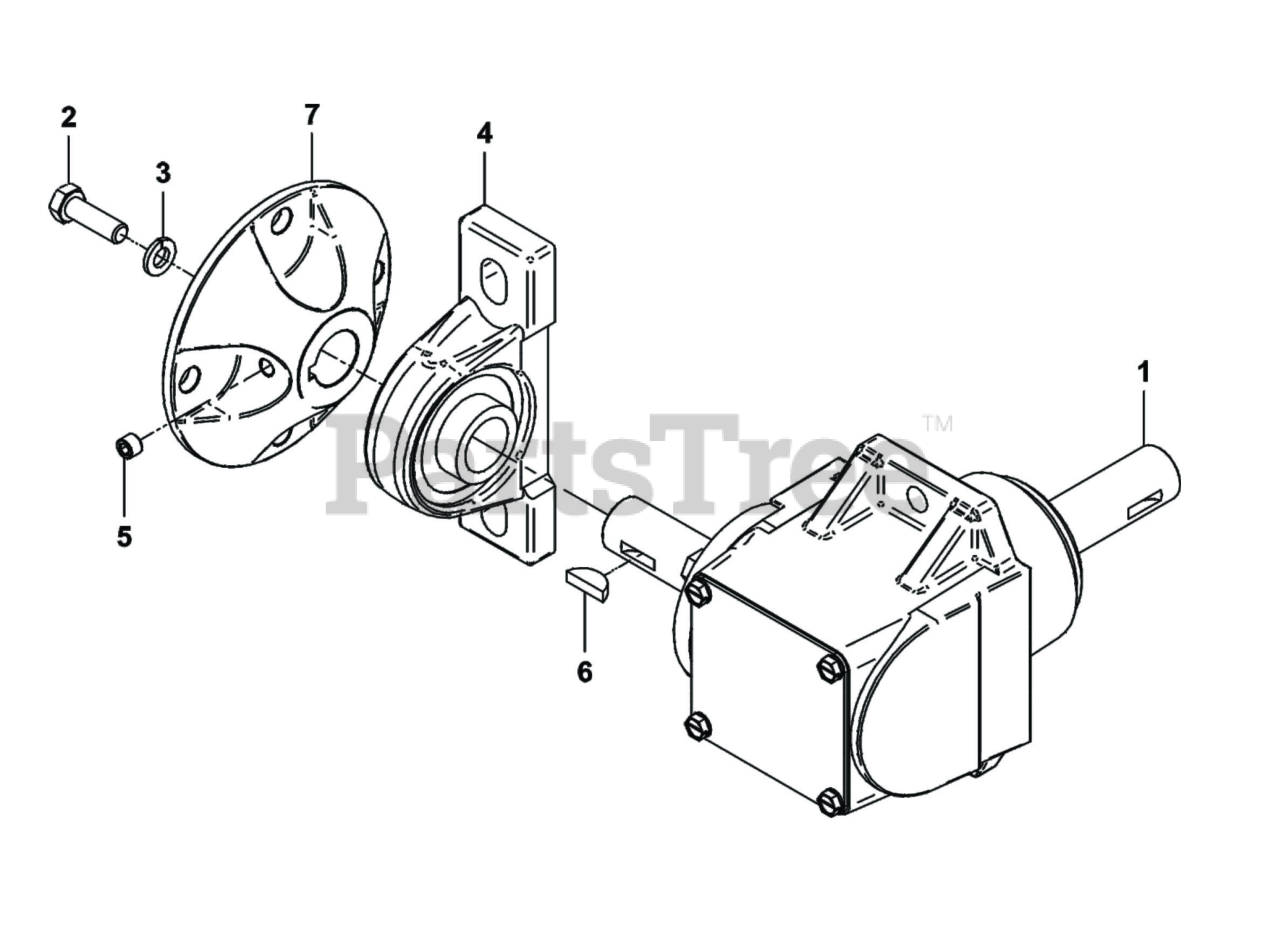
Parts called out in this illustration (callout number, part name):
2	SCREW 5/16"-24 GR8
3	LOCK WASHER 5/16"
4	PILLOW BLOCK BEARING 7/8"
5	SCREW-SET 5/16-18
6	WOODRUFF KEY #9
7	CLUTCH FLANGE ASSEMBLY
